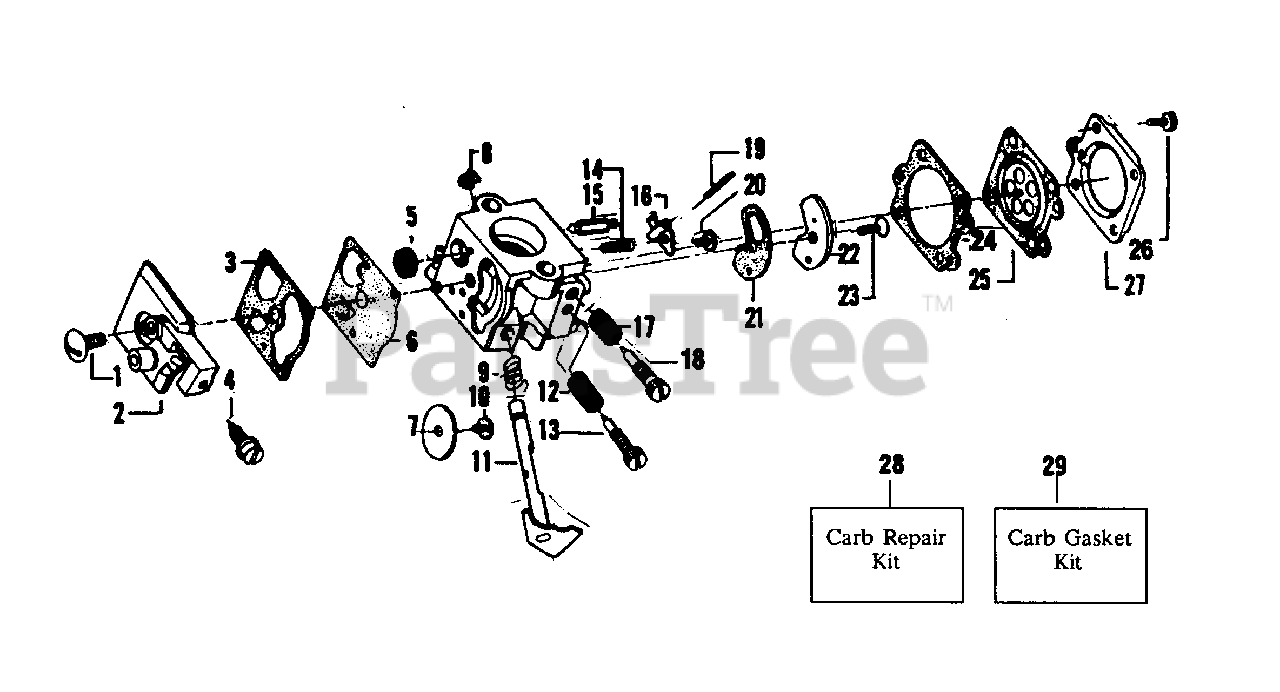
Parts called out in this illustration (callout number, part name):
1	Pump Cover Screw
2	Pump Cover Ass'y. (Inc.4)
3	Pump Gasket
4	Idle Adjustment Screw
5	Inlet Screen
6	Diaphragm Pump
7	Throttle Valve
8	Throttle Shaft Clip
9	Throttle Return Spring
10	Throttle Valve Screw
11	Shaft Ass'y. - Throttle
12	Idle Needle Spring
13	Idle Needle
14	Metering Lever Spring
15	Inlet Needle Valve
16	Metering Lever
17	Hi Speed Needle Spring
18	Hi Speed Needle
19	Metering Lever Pin
20	Metering Lever Pin Screw
21	Circuit Plate Gasket
22	Circuit Plate
23	Circuit Plate Screw
24	Metering Diaphragm Gasket
25	Metering Diaphragm Ass'y.
26	Metering Cover & Throttle Shaft Clip Ass'y. Screw
27	Metering Diaphragm Cover
28	Carb Kwik Repair Kit
29	Carb. Gasket/Diaphragm Kit
